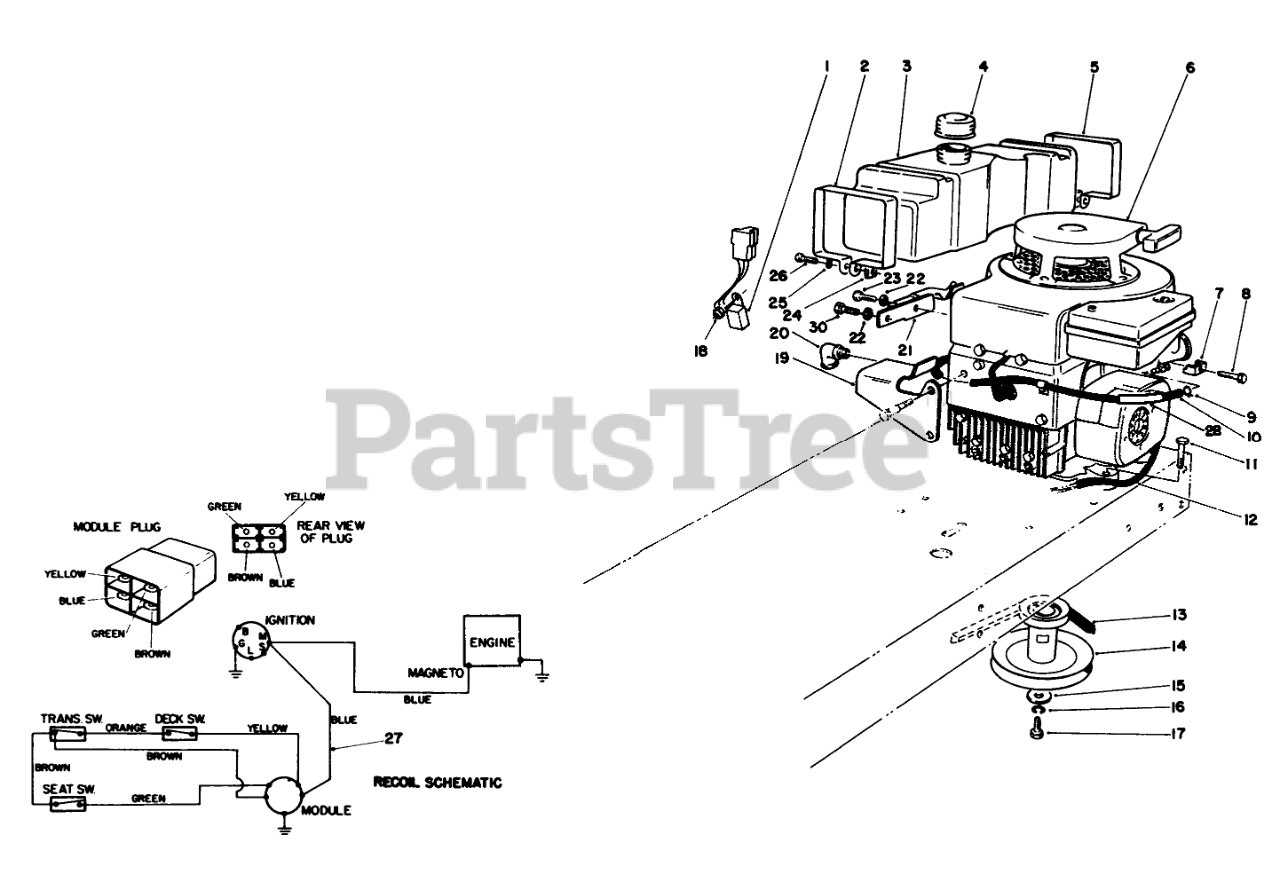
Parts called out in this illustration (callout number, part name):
1	INTERLOCK MODULE
2	Retainer-Tank Front
3	TANK-5 QT GAS
4	GAS CAP ASM
5	Retainer-Tank Rear
6	Engine
7	CLAMP-CASING
8	SCREW W ENGINE
9	CLAMP-HOSE
10	HOSE-FUEL
11	SCREW-HH
12	Cover-Protective
13	V-BELT, TRACTION
14	PULLEY
15	WASHER-FLAT
16	WASHER-LOCK
17	SCREW-HH
19	Bracket-Mount Tank Front
20	ELBOW-STREET, 90 DEG
21	Bracket-Mount Tank Rear
22	WASHER-PLAIN
23	SCREW-HH
24	NUT-SQUARE
25	WASHER-LOCK
26	SCREW-HSH
27	Wire Harness
28	SUPPORT-FUEL LINE
30	Screw
